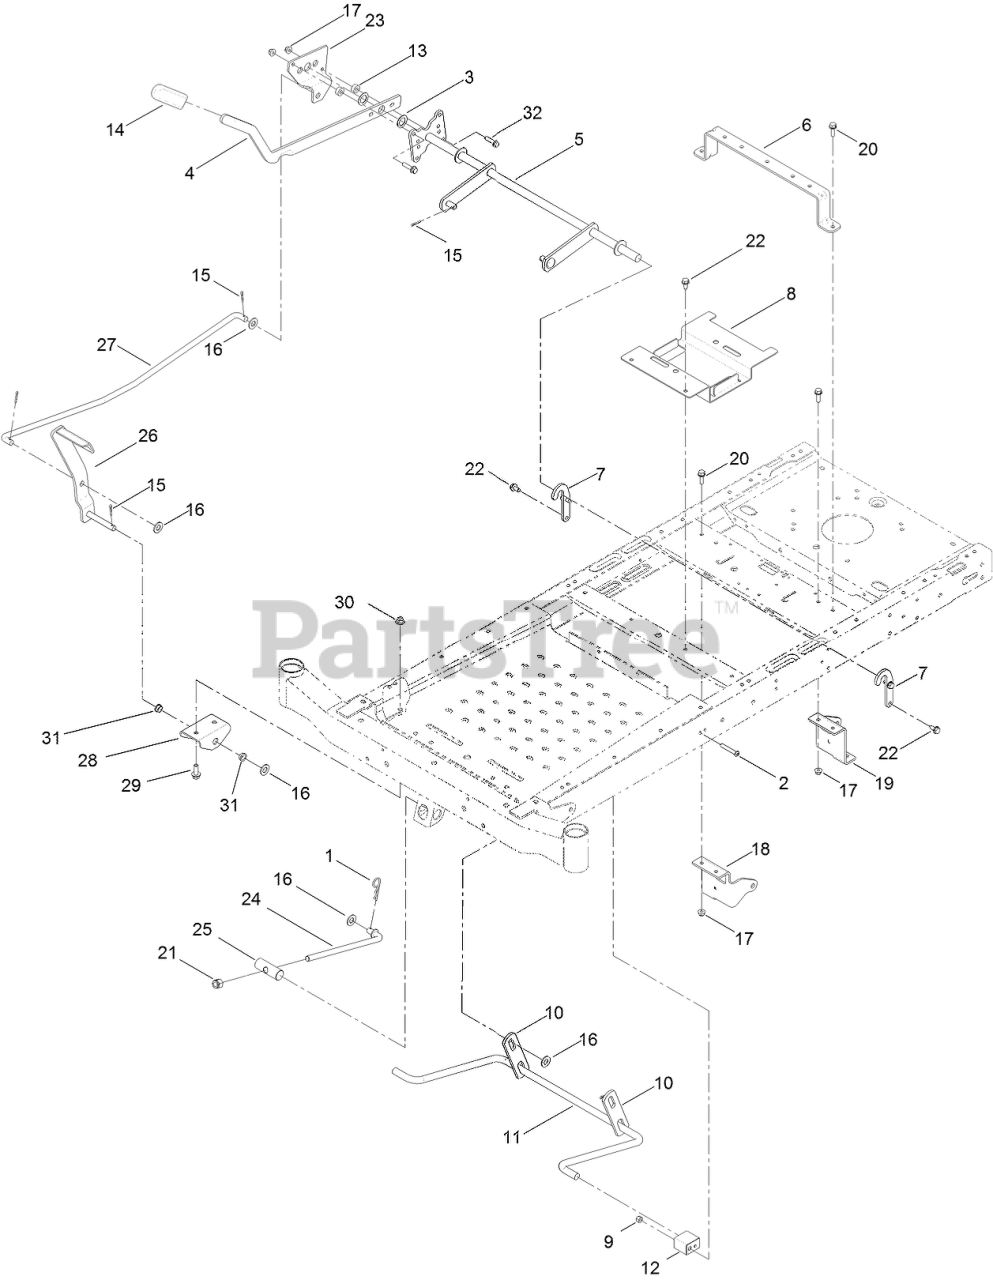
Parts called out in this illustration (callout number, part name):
1	PIN-COTTER
2	SCREW-HSBH
3	WASHER-THRUST
4	LEVER-LIFT
5	LIFT-DECK, WIDE
6	BRACE-SEAT, REAR
7	BRACKET-LIFT
8	BRACKET-BATTERY
9	NUT-LOCK, NI
10	LINK-LIFT
11	ARM-LIFT, REAR (WIDE)
12	BLOCK-PIVOT
13	SPACER
14	GRIP-LEVER
15	PIN-COTTER
16	WASHER-FLAT
17	NUT-HF, NI
18	MOUNT-HYDRO, FRONT (RH)
19	MOUNT-HYDRO, FRONT (LH)
20	SCREW-HHF
21	NUT-HEX
22	SCREW-HWHTF
23	PLATE-FOOTLIFT
24	ROD-TRUNION
25	PIN-PIVOT
27	ROD-FOOTLIFT
28	BRACKET-FOOTLIFT
29	SCREW-HHF
30	NUT-HF, NI
31	BUSHING-FLANGE
32	SCREW-HHF
